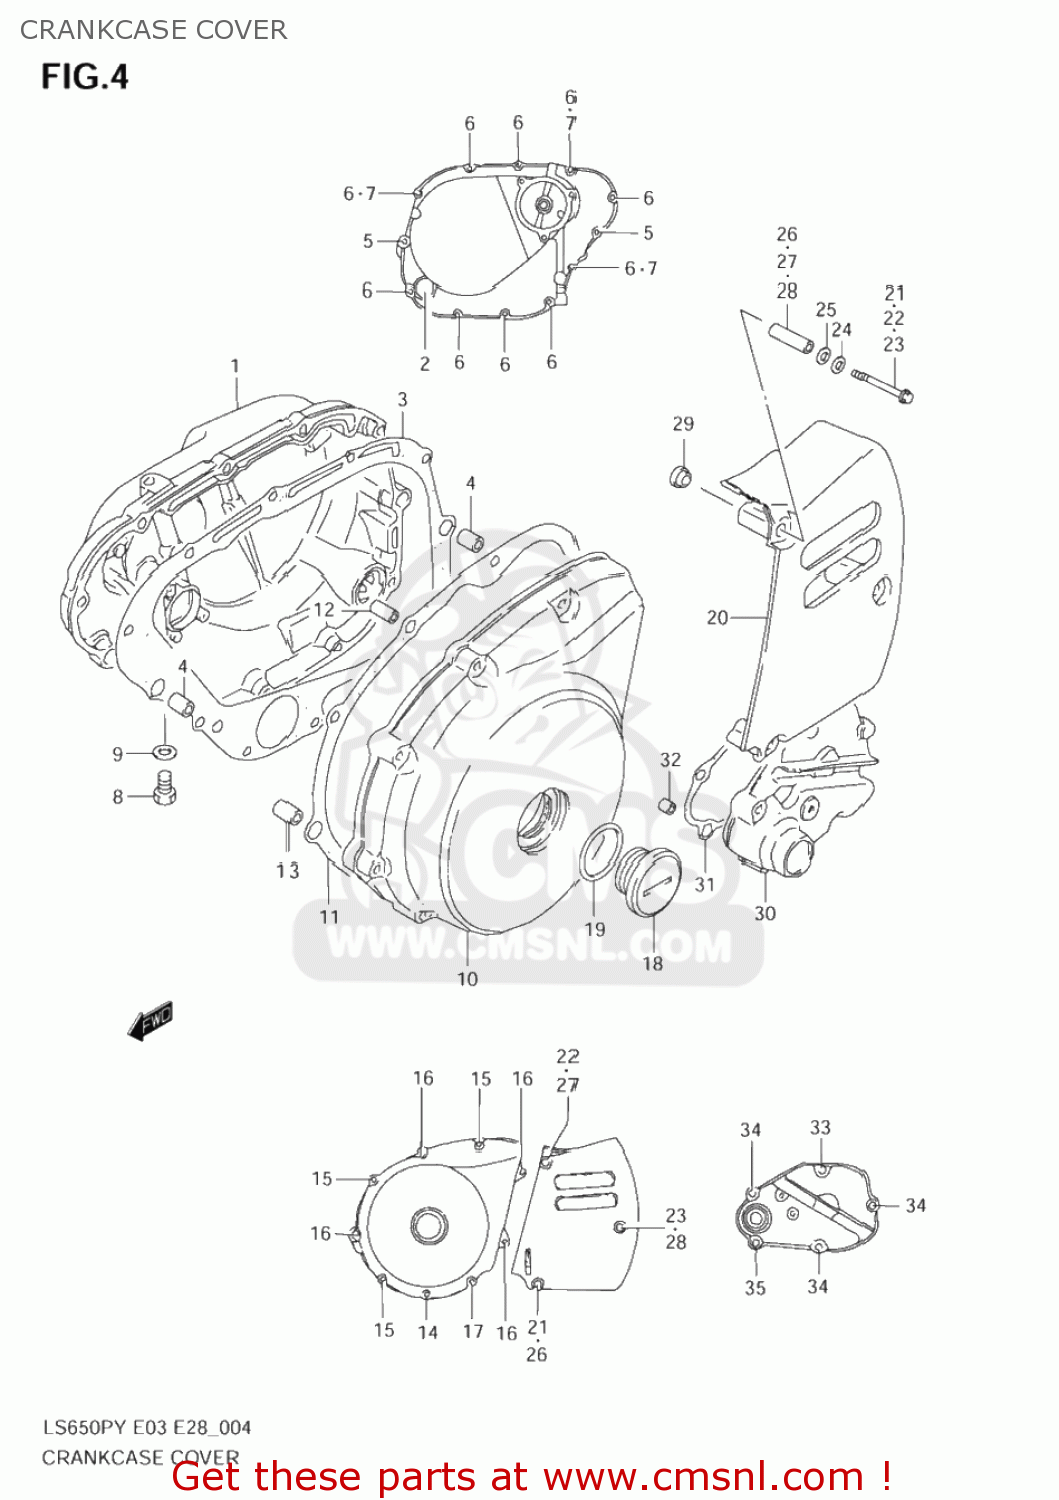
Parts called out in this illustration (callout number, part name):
1	COVER,CLUTCH
2	LENS,OIL LEVEL CHECK
3	GASKET,CLUTCH COVER (NAS)
4	PIN
5	BOLT
6	BOLT
7	GASKET(5.8X11X1.2) (NAS)
8	PLUG,12X9
9	GASKET(12.1X16.2X3.7) (NAS)
10	COVER,GENERATOR
11	GASKET,GENERATOR COVER (NAS)
12	PIN
13	PIN
14	BOLT
15	BOLT
16	BOLT
17	BOLT
18	PLUG,36X10
19	O RING(D:3.1,ID:32.7)
20	COVER,ENGINE SPROCKET
21	BOLT
22	BOLT
23	BOLT
24	WASHER
25	WASHER(8.7X15X2.1)
26	SPACER(6.5X9X31.5)
27	SPACER(6.5X9X38.3)
28	SPACER(6.5X9X41.3)
29	WASHER(8.7X16X5)
30	COVER,GEAR SHIFT
31	GASKET,GEAR SHIFT COVER (NAS)
32	PIN
33	BOLT
34	BOLT,G/S SWITC
35	BOLT
